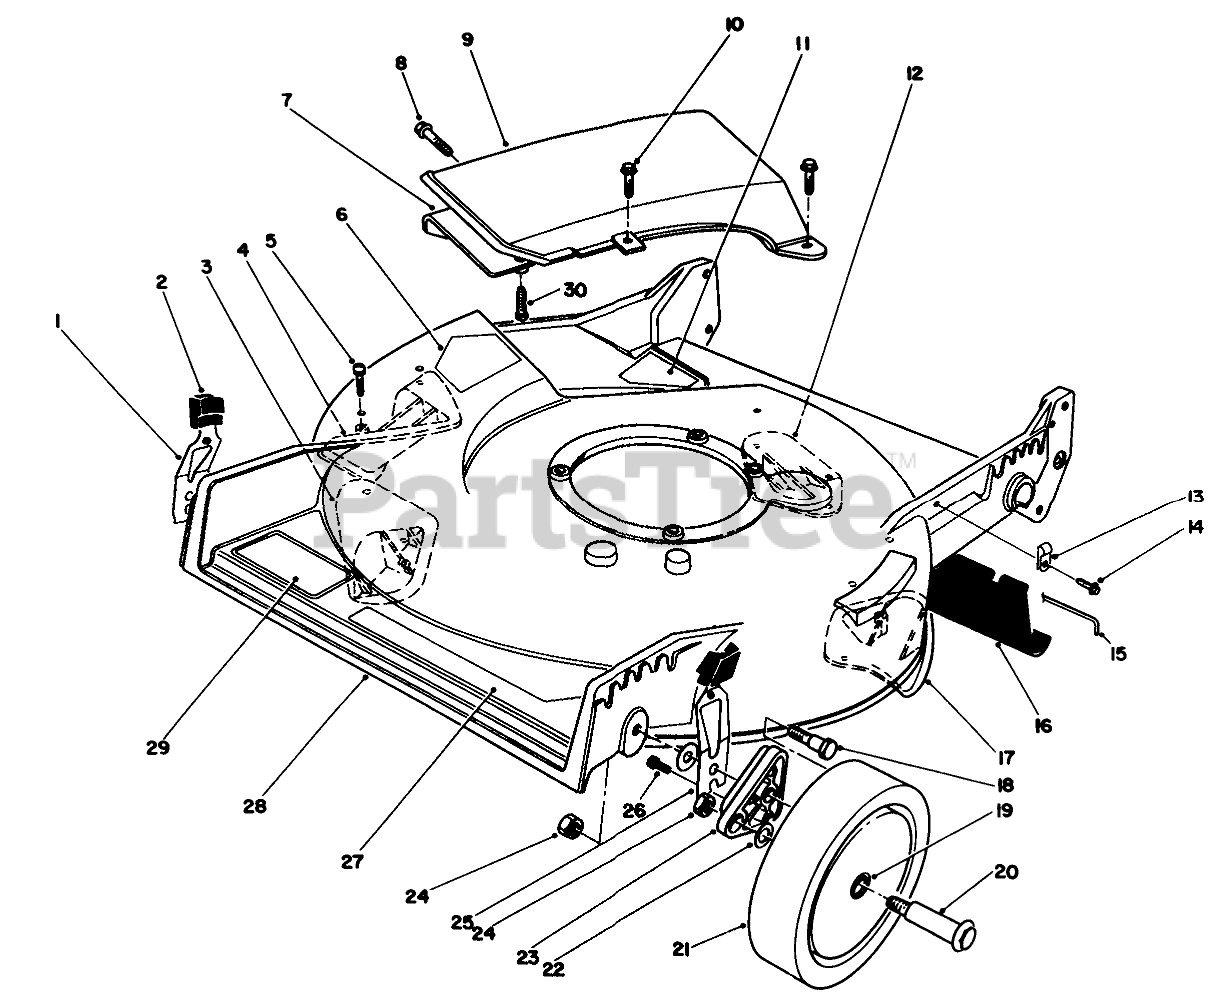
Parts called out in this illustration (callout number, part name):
1	RH SPRING ARM ASSEMBLY
2	KNOB-ARM
3	KICKER
4	KICKER
5	SCREW-PPH
6	DECAL-DANGER
7	Deflector-Recycler
8	SCREW AND WASHER ASM
9	Cover Assembly (Incl. Ref #7 & 19)
10	SCREW-HWH
11	DECAL - DANGER
12	PLATE-KICKER
13	CLAMP-R
14	SCREW-HWH
15	ROD-SHIELD
16	SHIELD-TRAILING
17	KICKER
18	SCREW-SHOULDER
19	BUSHING
20	WHEEL BOLT
21	Wheel & Tire Assembly (Incl. Ref. #19)
22	WASHER
23	ARM-PIVOT, FRONT
24	Nut
25	LH SPRING ARM ASSEMBLY
26	SCREW-HWH
27	DECAL - DECK
28	Housing Assembly (Incl. Ref. #3, 4-6, 12, & 17)
29	DECAL
30	Screw-Pan
